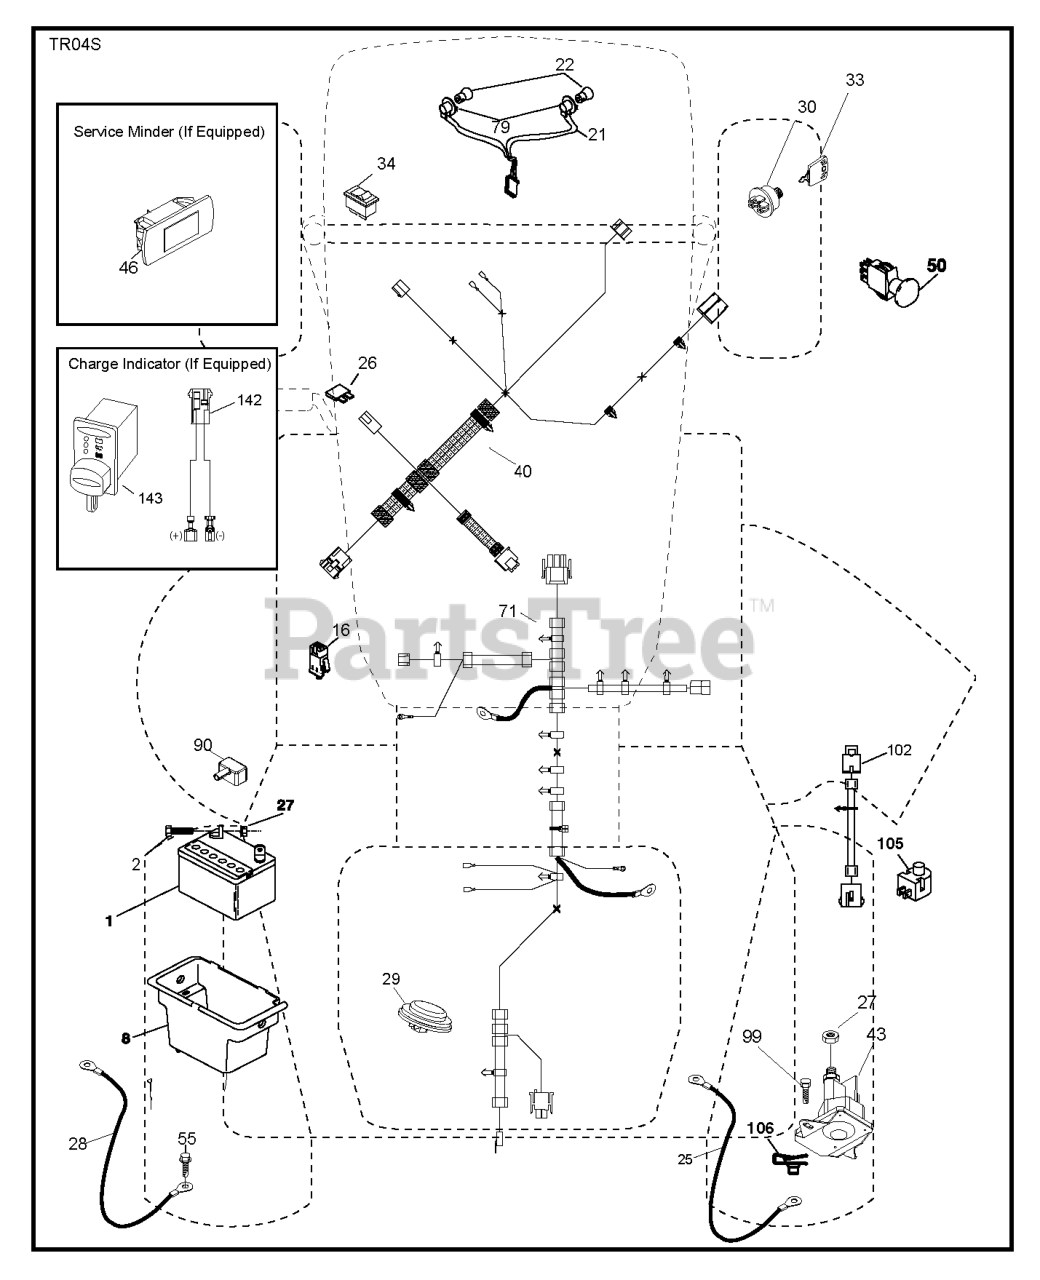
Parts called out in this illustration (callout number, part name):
1	Battery 12 Volt 25 Amp
2	BOLT.HEX.1/4.X.3/4.DICHROMATE
8	BOX.BATTERY.MNT.REAR.L
16	SWITCH INTERLOOK PUSH-IN
21	HARNESS.LIGHT W/4152J BULBS
25	CABLE.BATT.RED.8GA.17
26	FUSE 20AMP
27	NUT
28	CABLE.GROUND.REAR.BATTERY.8G
29	SWITCH.SEAT.DELTA.OPC.
30	SWITCH.IGN.DELTA.W.LGH.ROS
33	KEY.CHAIN.BLISTER.PACK.GEN.INT
40	HARNESS.DASH.RRBATT.EL.CHG
43	SOLENOID.STARTER.BRASS.PLUNGER
46	GUAGE.SRVCMNDR.HRMTR.
50	SWITCH.PTO.8TERMINAL.STD.BLK
55	SCREW 5/16"
71	HARNESS.CHASSIS.RRBATT.RDYSTRT
79	BULB HOLDER ASM.
90	COVER.TERMINAL.BATTERY
99	SCREW HEXWSHR 1/4-20X3/4
102	HARNESS PIGTAIL PCH TEX ROS
105	REVERSE SWITCH
106	1/4-20 U NUT
142	CHARGE.PORT.PIGTAIL HARNESS
143	CHARGE.PORT
